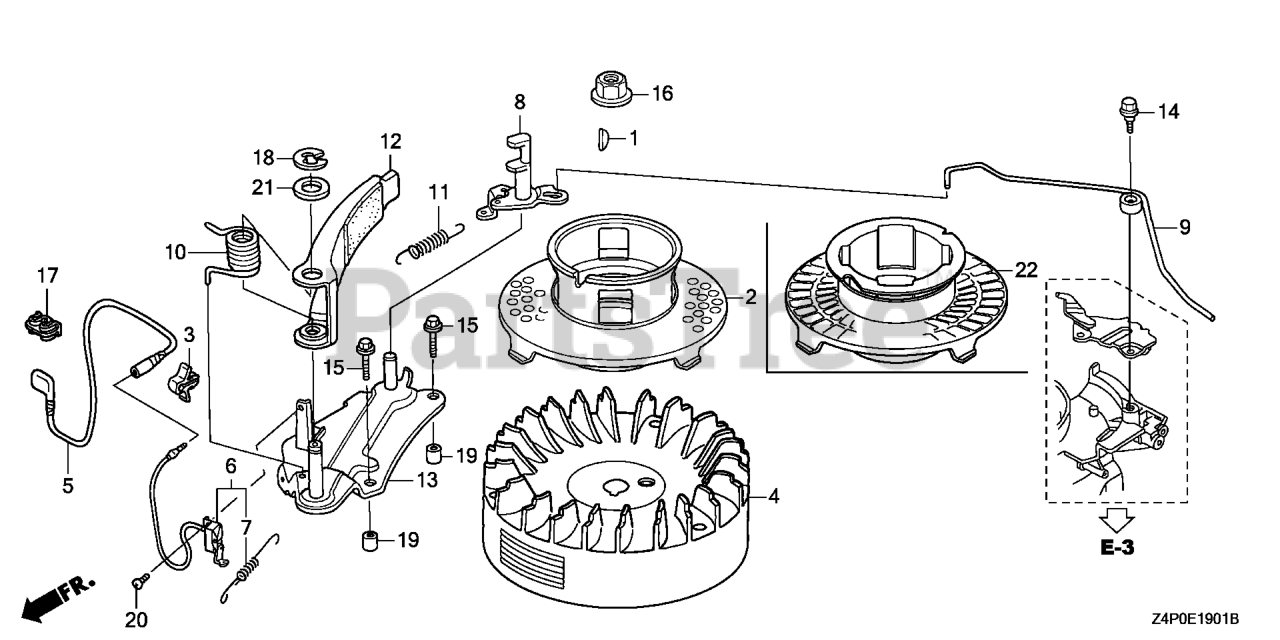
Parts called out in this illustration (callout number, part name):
1	KEY, SPECIAL WOODRUFF (25X18)
3	CLIP, IGNITION WIRE (8MM)
4	FLYWHEEL (BRAKE)
5	WIRE, STOP SWITCH (BRAKE)
6	SWITCH ASSY., ENGINE STOP (BRAKE)
7	SPRING, SWITCH CONTROL
8	CAM, BRAKE
9	ROD, THROTTLE RETURN
10	SPRING, BRAKE
11	SPRING, BRAKE RETURN
12	BRAKE
13	BASE, BRAKE
14	BOLT, FLANGE (6MM)
15	BOLT, FLANGE (6X23)
16	NUT, SPECIAL (14MM)
17	CLAMP, PIPE
18	E-RING (10MM)
19	PIN, DOWEL (8X9)
20	SCREW, PAN (4X8)
21	WASHER, PLAIN (12MM)
22	PULLEY, STARTER
